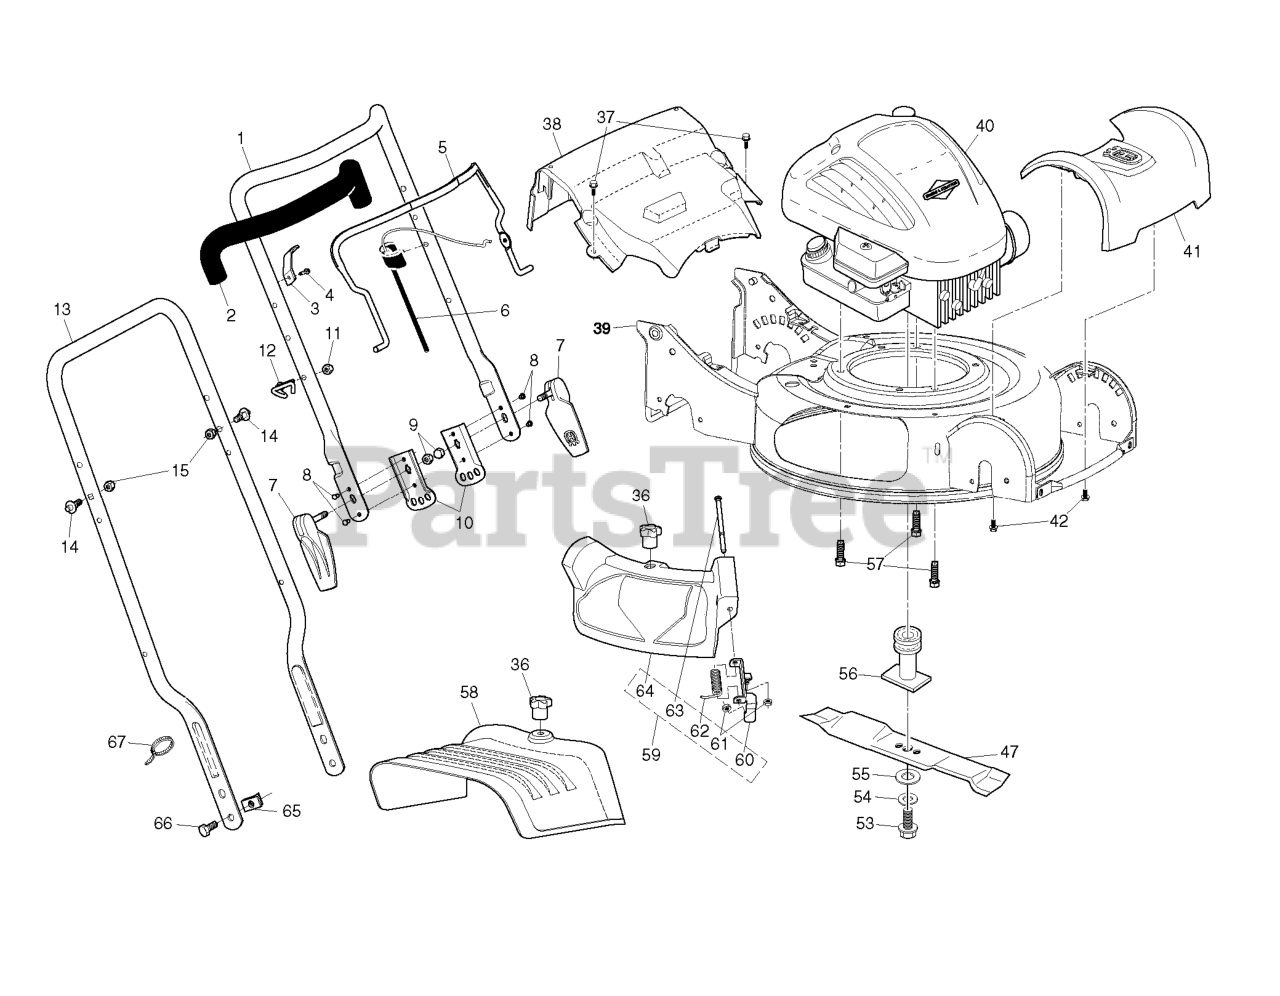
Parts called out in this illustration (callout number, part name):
2	GRIP, FOAM
3	BRACKET.UPSTOP.RT
5	BAIL.CONTROL.MZR.BS.ORANGE
6	CONTROL.ZONE.ASM
7	ASM.QUICK.RELEASE
9	Locknut, Hex 1/4-20
10	BRACKET.ADJ.3POS.GREY
11	NUT
12	RB GUIDE.ROPE.STD.BLK.ZIN WSL
14	STUD.QUICK.ADJUST
15	NUT.LOCK.5/16-18
36	KNOB.MULCH.DOOR
37	SCREW, HEX WASHER HEAD
42	SCREW.HWH.13-16-5.8.BZP
53	BOLT.HD.HEAD.3/8-24X2.50 (2 2)
54	LOCKWASHER
55	WASHER,HARDEN
57	BOLT 3/8-16X1-1/8
61	NUT.HEX.FLANGE.1/4
62	SPRING.MULCH.DOOR
63	ROD.HINGE.1/4"3.82"
64	DOOR.MULCH.GREY
67	TIE GUIDE
